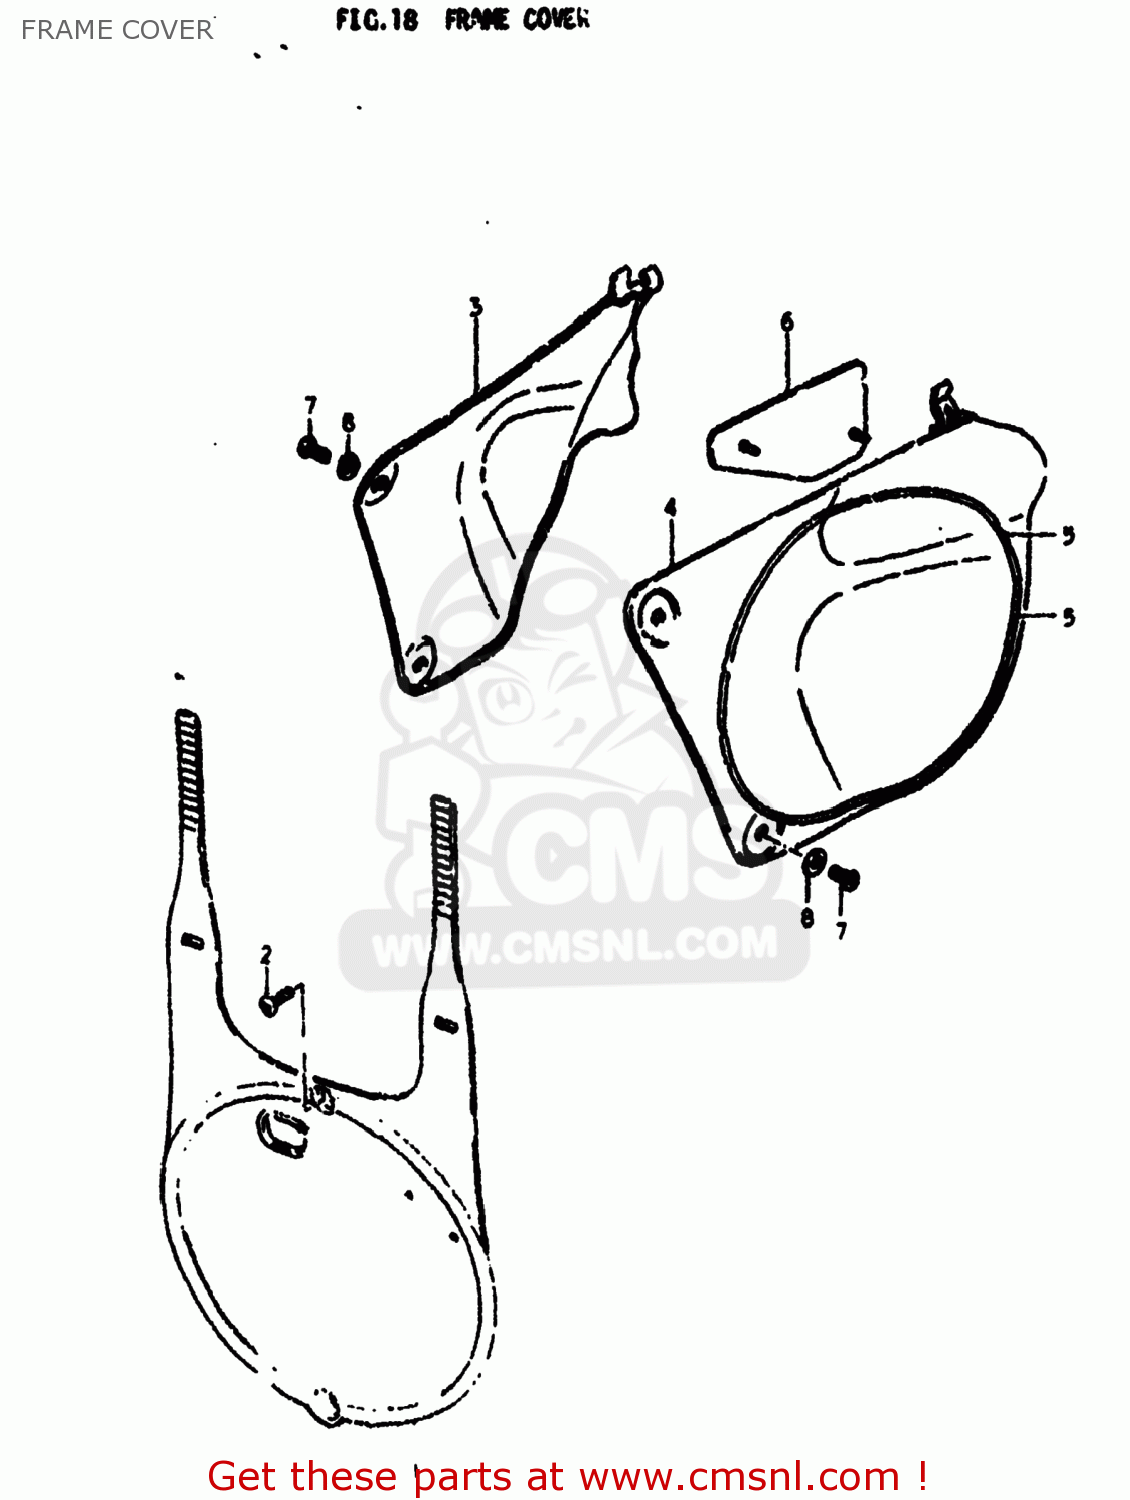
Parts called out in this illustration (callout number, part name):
1	PLATE,FR NUMBER
2	(5X20) CROSS SCREW
3	COVER,FRAME,RIGHT
4	COVER,FRAME,LEFT
5	TAPE,FRAME COVER
7	SCREW 6X12
8	WASHER
